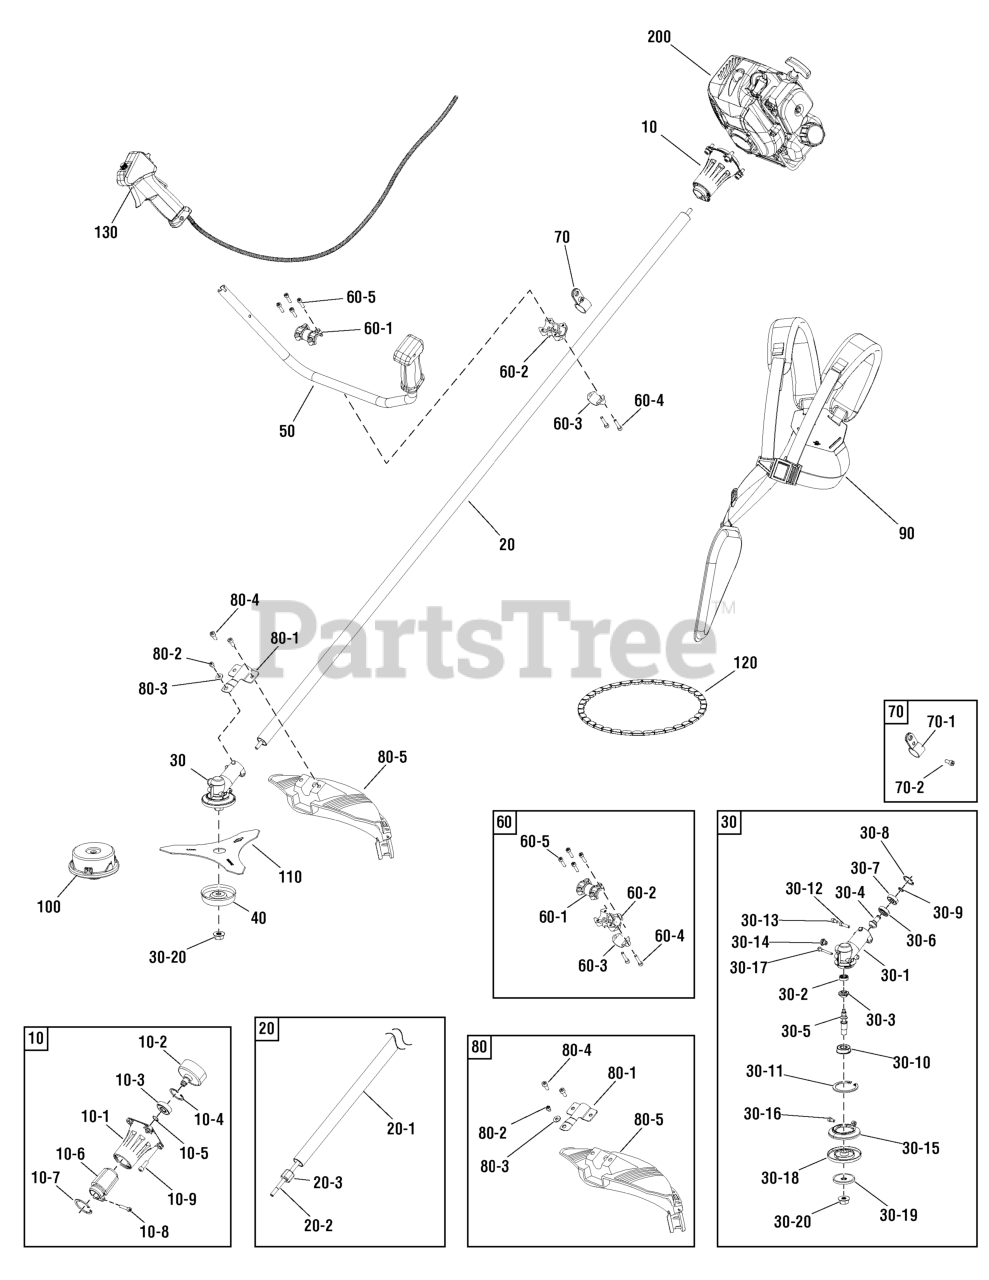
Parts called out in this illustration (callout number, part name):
10	CLUTCH HOUSING ASSEMBLY
10-1	HOUSING, Clutch
10-2	CLUTCH DRUM
10-3	BEARING
10-6	COUPLER
20	SHAFT ASSEMBLY
20-1	SHAFT
20-2	DRIVE SHAFT
20-3	BUSH
30	GEARBOX ASSEMBLY
30-1	HOUSING, Gear Case
30-2	BEARING
30-3	GEAR
30-4	PINION
30-5	SHAFT
30-6	BEARING
30-7	BEARING
30-10	BEARING
30-14	PLUG
30-15	COVER
30-17	BOLT, Special
30-18	BLADE HOLDER
30-19	BLADE HOLDER
30-20	NUT
50	HANDLE ASSEMBLY
60	HANDLE BRACKET ASSEMBLY
60-1	BRACKET, Handle, Upper
60-2	BRACKET, Handle, Lower
60-3	BRACKET, Shaft
70	HANGER ASSEMBLY
70-1	HANGER
80	GUARD ASSEMBLY
80-1	BRACKET
80-2	BOLT
80-3	WASHER
80-5	GUARD
90	SHOULDER STRAP
100	BUMP HEAD
110	BLADE, 3T
120	COVER, Blade
130	LEVER ASSEMBLY, Throttle
200	ENGINE
